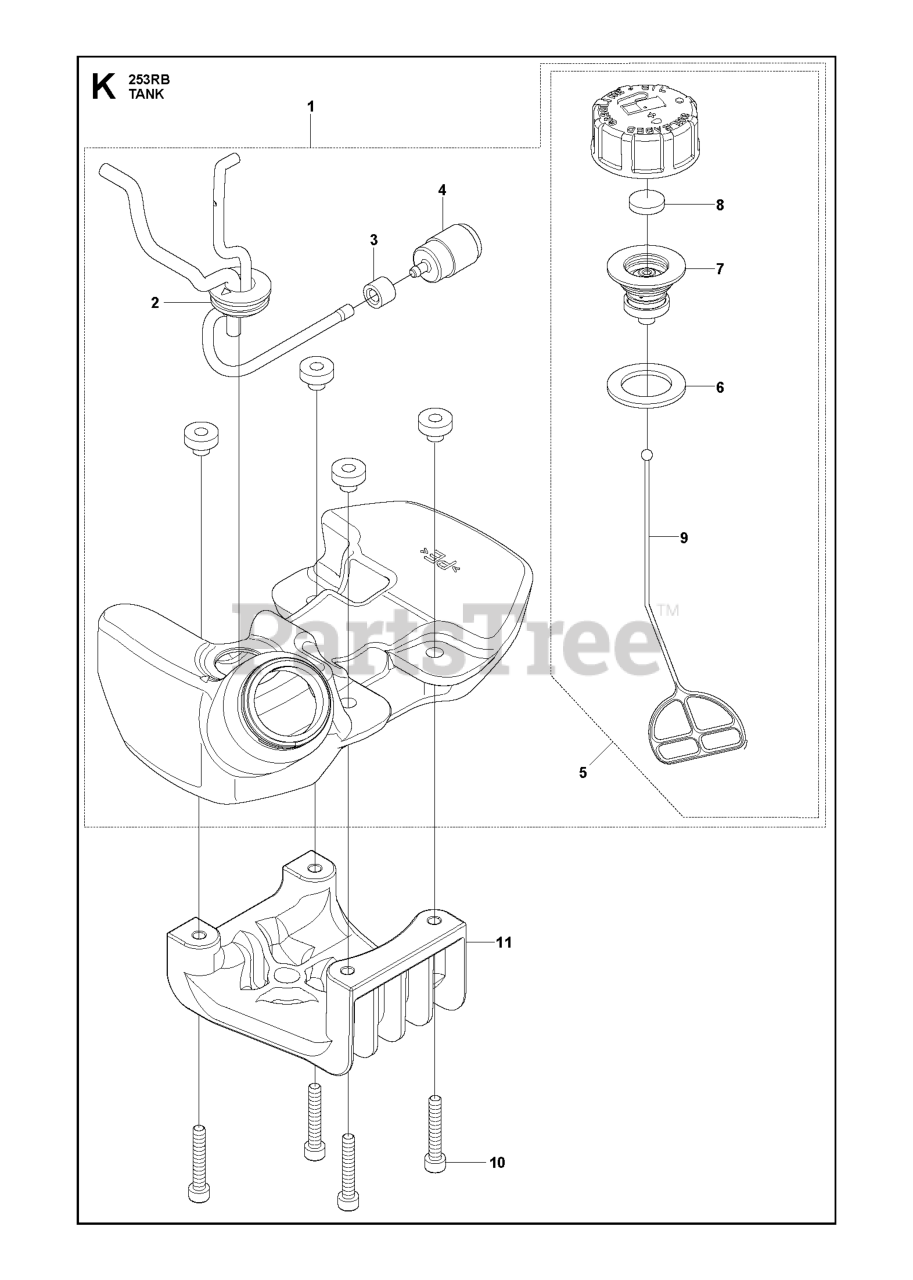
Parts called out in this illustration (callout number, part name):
4	FILTER
5	CAP ASSY
6	PACKING
7	HOLDER ASSY
8	FILTER
9	STOPPER
